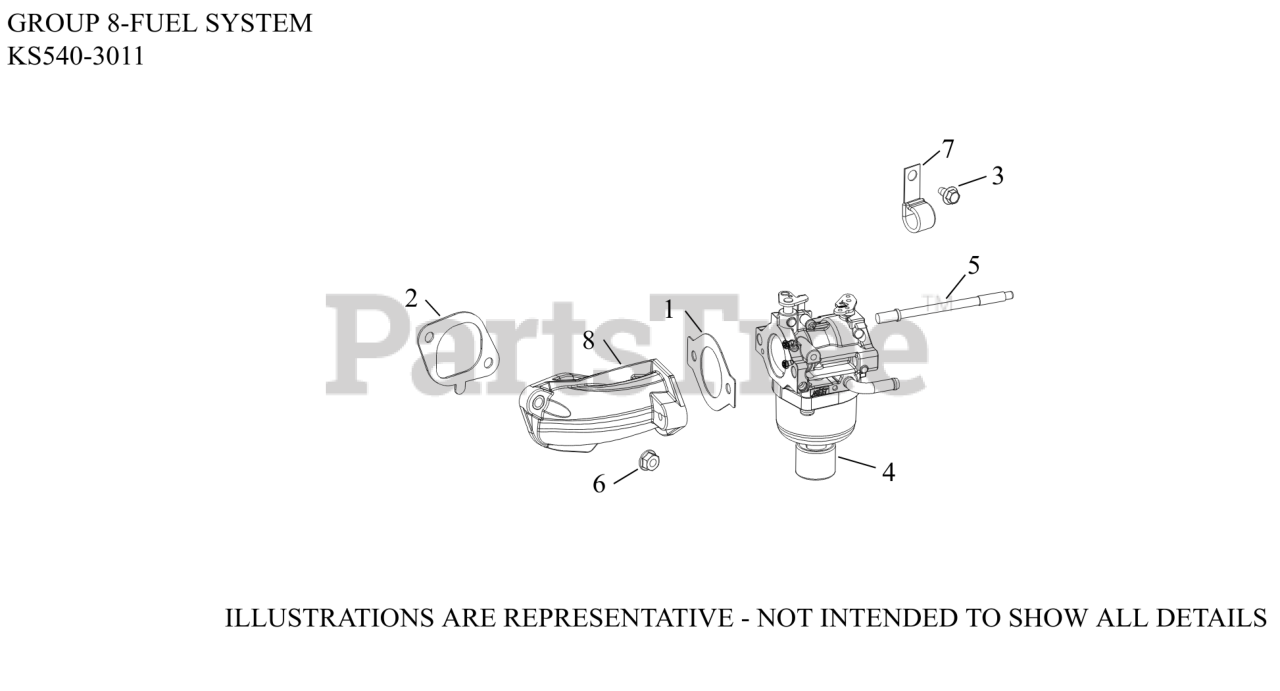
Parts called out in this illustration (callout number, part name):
1	GASKET, CARBURETOR (THROTTLE)
2	GASKET, INTAKE MANIFOLD
3	SCREW, THREAD FORMING
4	KIT,CARB(NIKKI)
5	STUD, CARBURETOR
6	NUT, FLG M6X1.0
7	CLIP, CABLE
8	MANIFOLD, INTAKE ASSEMBLY
NI	HIGH ALTITUDE KIT (5000 FT)
NI	KIT, OVERHAUL
NI	KIT, CHOKE SHAFT
NI	KIT, O-RING
NI	KIT, SOLENOID (NIKKI)
NI	KIT, BOWL WITH O-RINGS
NI	KIT, FLOAT AND INLET NEEDLE FOR GRAVITY
NI	KIT, THROTTLE SHAFT
NI	MASKING CAP
